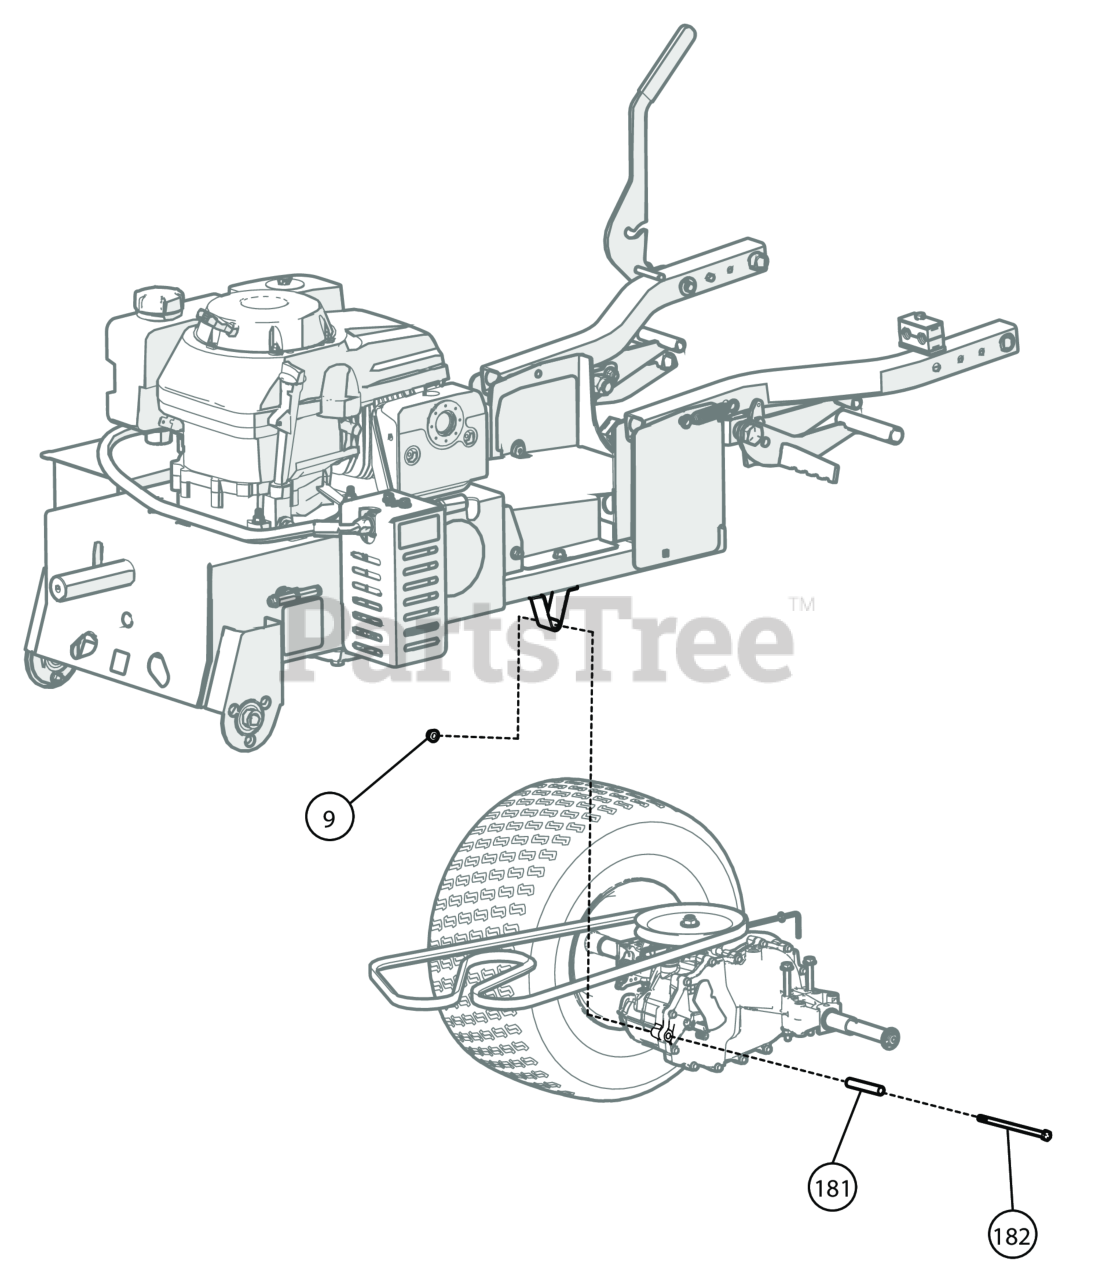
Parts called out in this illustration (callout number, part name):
9	NUT-HEX-NYLK, FLG .3125-18 ZP
181	SPACER, ANTI-ROTATION MOUNT
182	SCR-CAP, HEX-UNC, .3125-18 X 6.0
